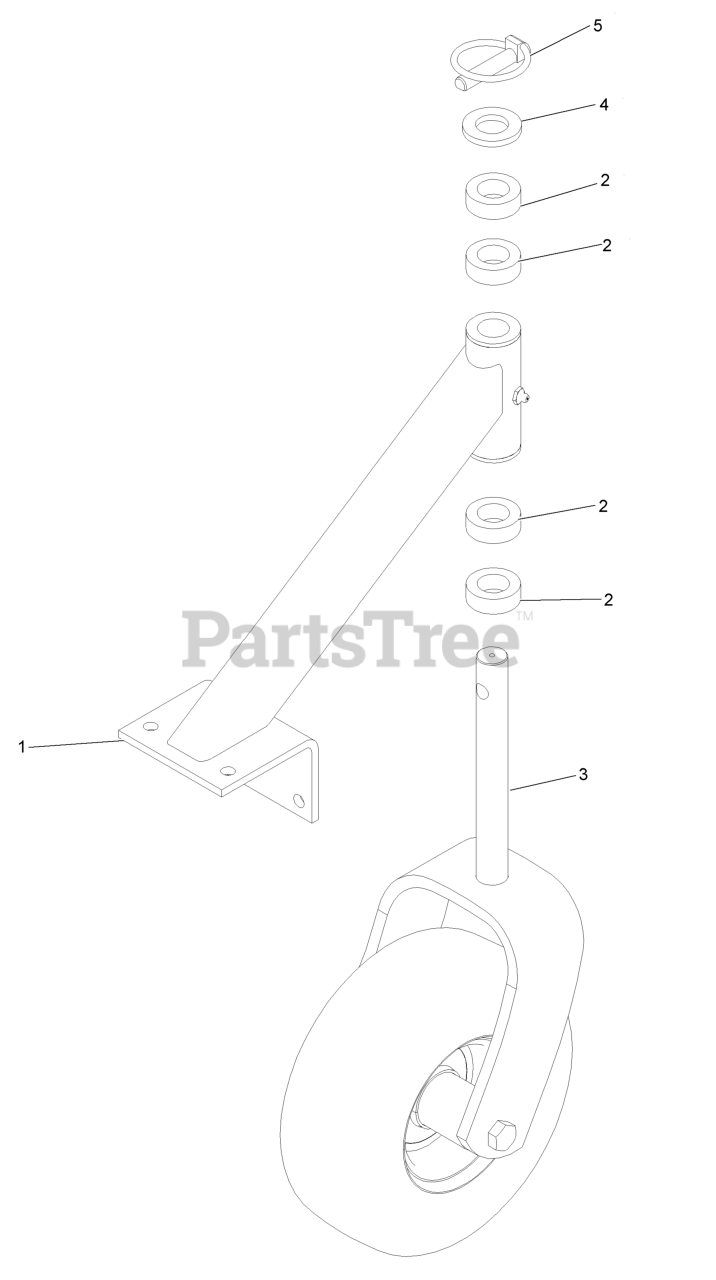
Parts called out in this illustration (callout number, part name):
1	Support ASM
2	Spacer-Caster
3	Caster Wheel Assembly
4	Washer-Flat
